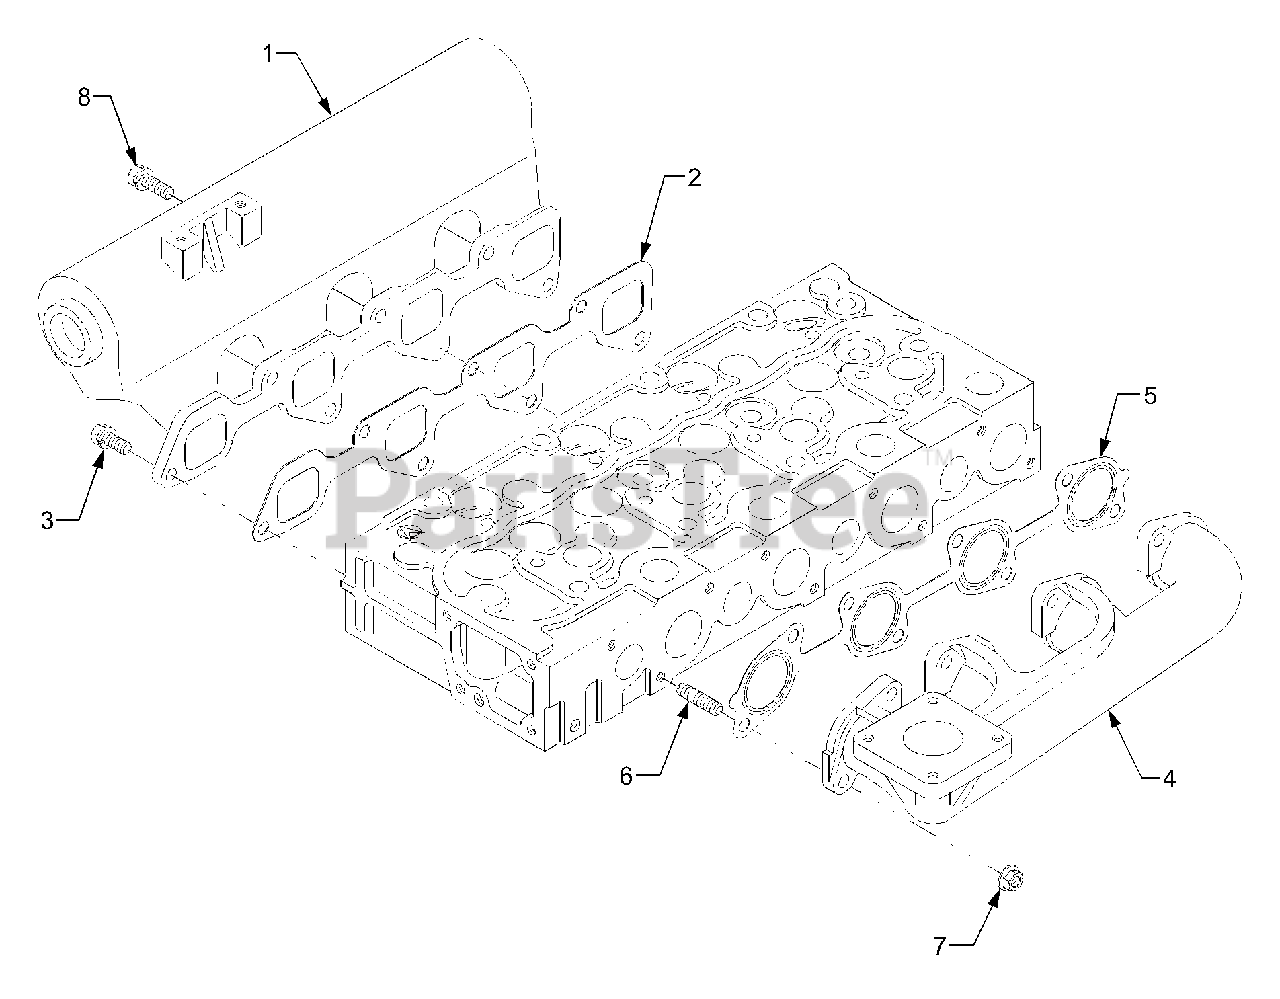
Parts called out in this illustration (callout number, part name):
1	Manifold, Inlet
2	Gasket, Inlet Manifold
4	Manifold, Exhaust
5	Gasket,Exhaust Manifold
